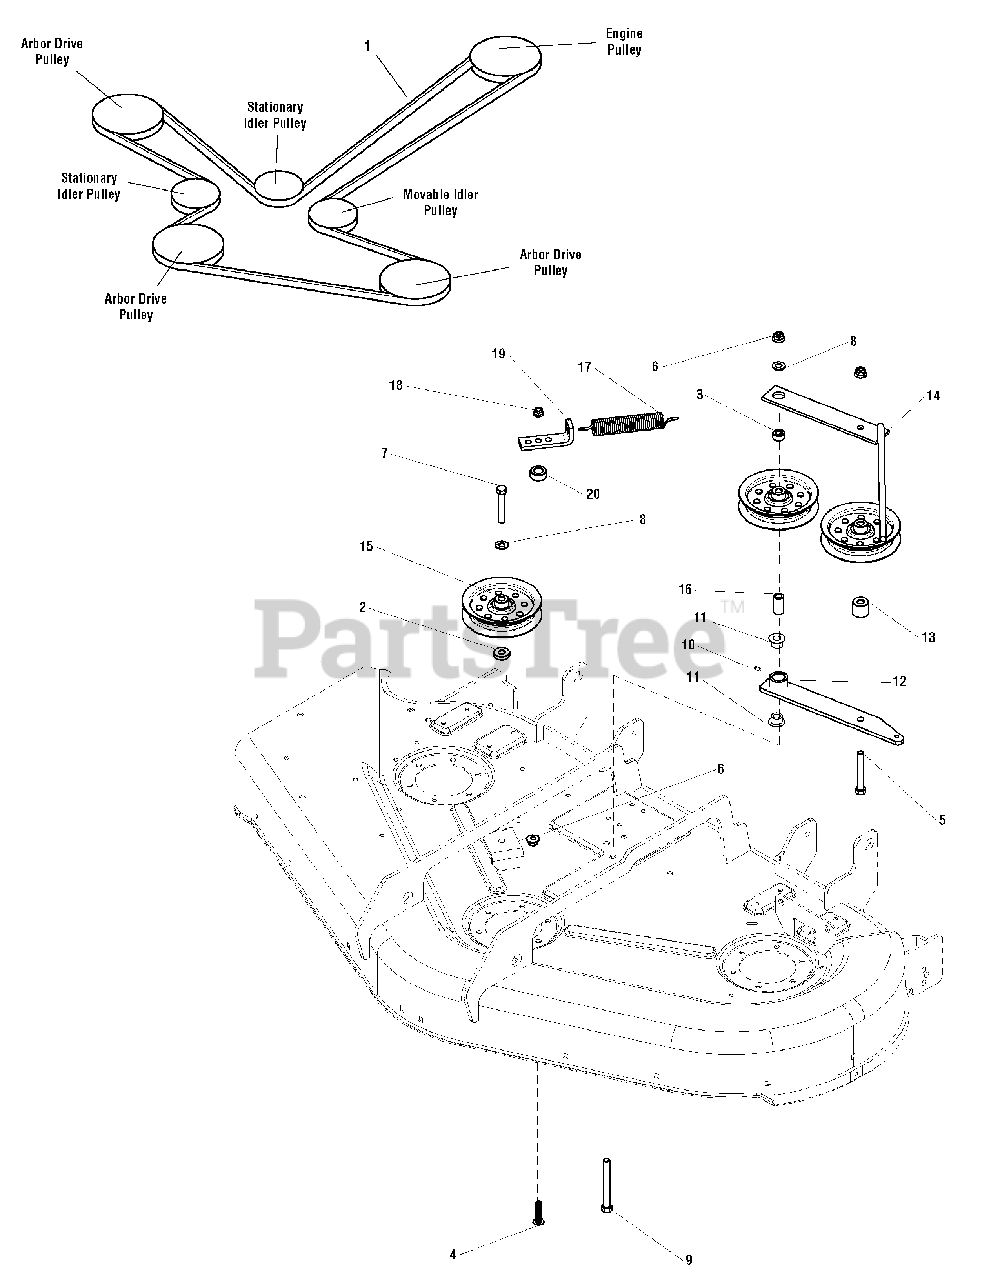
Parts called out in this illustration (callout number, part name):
1	BELT (155" E. L. For 50" Deck)
1	BELT (151" E. L. For 44" Deck)
2	SPACER, .39 X 1.00 X .25
3	SPACER, .39 X .75 X .38
4	BOLT, 5/16-18 X 1-1/2" FLANGE
5	BOLT, 3/8-16 X 2-3/4" GD5
6	NUT, 3/8-16 HEX NYLOCK FLANGE
7	BOLT, 3/8-16 X 2-1/4" GD5
8	WASHER, 3/8 SAE
9	BOLT, 3/8-16 X 3-1/2" GD5
10	FITTING, Grease
11	BUSHING, 5/8 X 3/4 X 13/32, POWDER METAL
12	ASSM, IDLER ARM 44" SIMPLICITY
13	SPACER, .39 X 1.00 X .88
14	WELD, MOUNT, IDLER, TENSION
15	ASSM, PULLEY IDLER
16	Spacer
17	SPRING, EXTEN, 1.0 OD, 6" LG, .118
18	NUT, 5/16-18 HEX NYLOCK FLANGE
19	ANCHOR, SPRING
20	SPACER, .52 X 1.00 X .44
